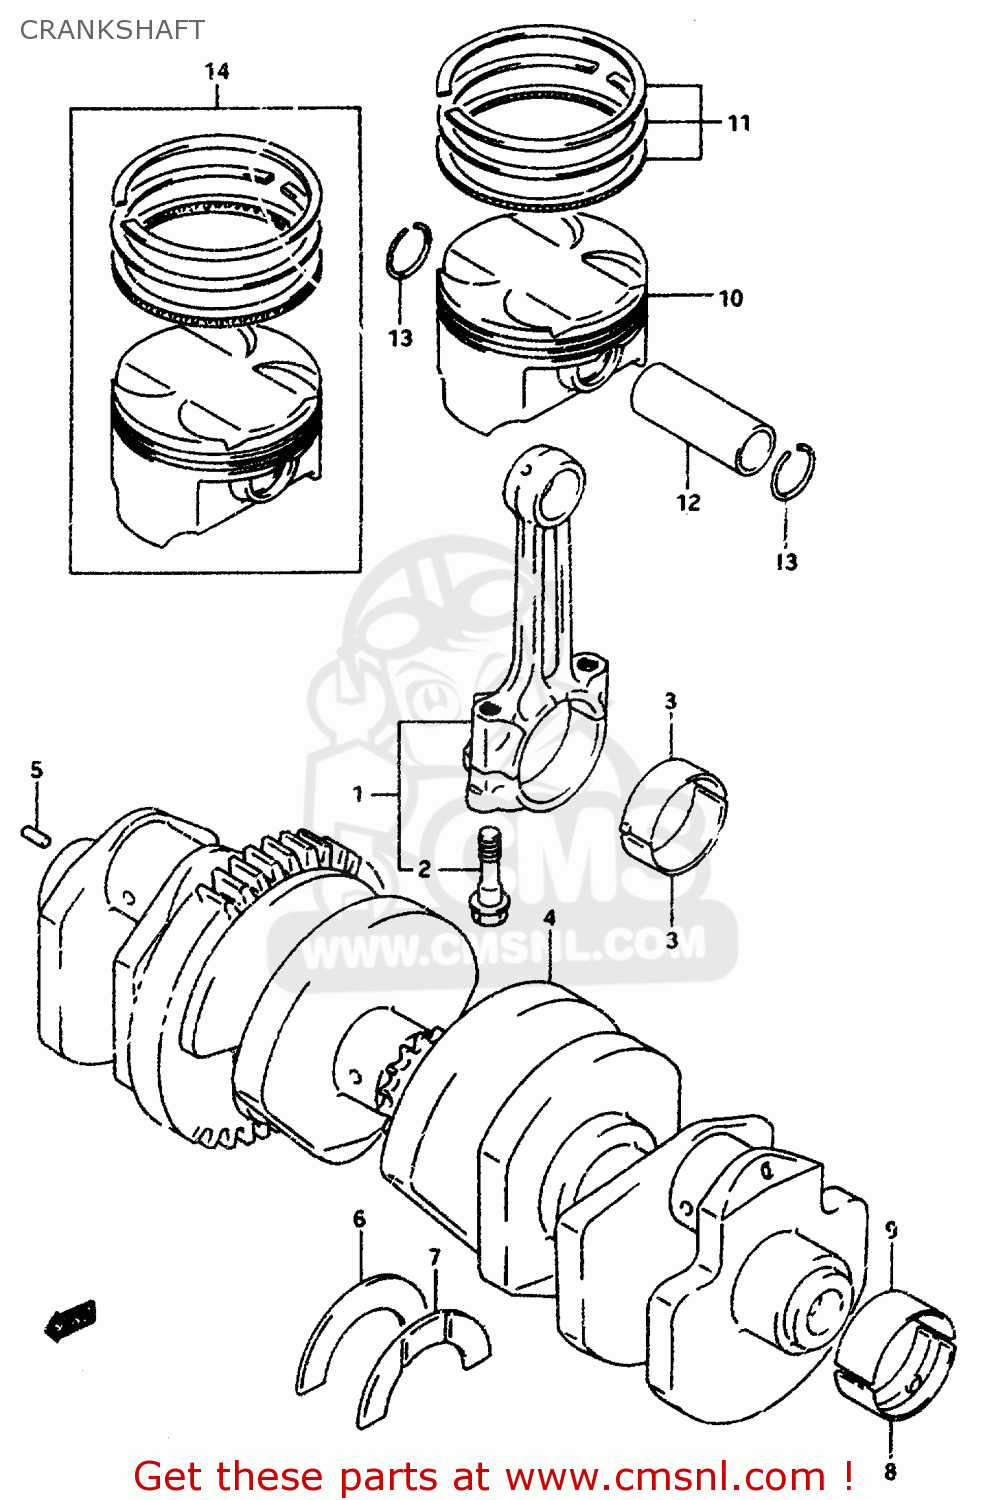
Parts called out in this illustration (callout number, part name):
1	CONNECTING ROD ASSY
2	BOLT,CONNCTING ROD
3	BEARING,CRANK PIN
4	CRANKSHAFT SET
5	PIN
6	BEARING,CRANK THRUST(GREEN)
7	BEARING,CRANK THRUST(RED)
8	BEARING,CRANKSHAFT LWR
9	BEARING,CRANKSHAFT UPR
10	PISTON
11	RING SET,PISTON
12	PIN,PISTON
13	CIRCLIP,PISTON PIN
14	PISTON SET(OS:0.5)
